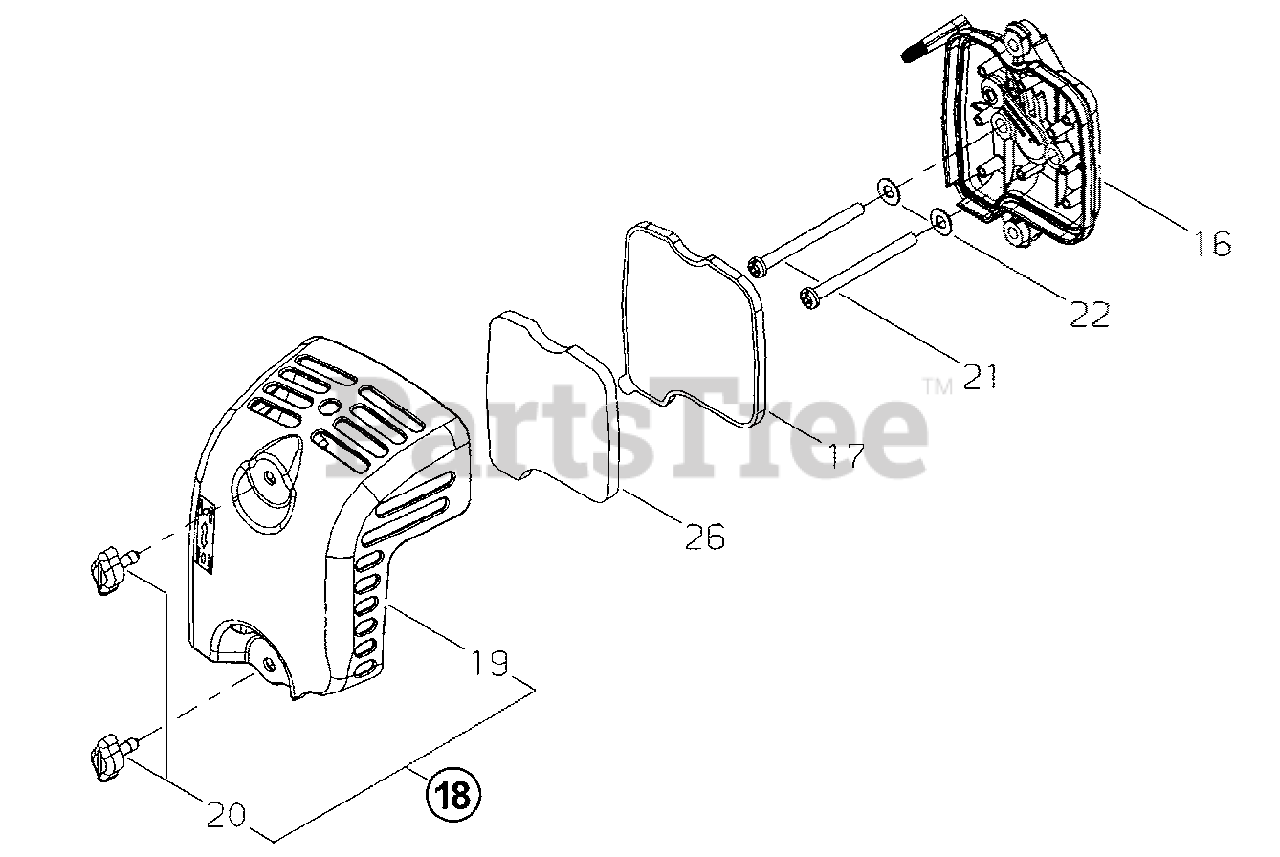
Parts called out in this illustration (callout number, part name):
16	CASE ASSY, AIR FILTER
17	FILTER, AIR
18	COVER ASSY, AIR FILTER
19	COVER, AIR FILTER
20	THUMBSCREW M5
21	SCREW M5×60
22	WASHER 5 MM
26	PRE-FILTER, FOAM
